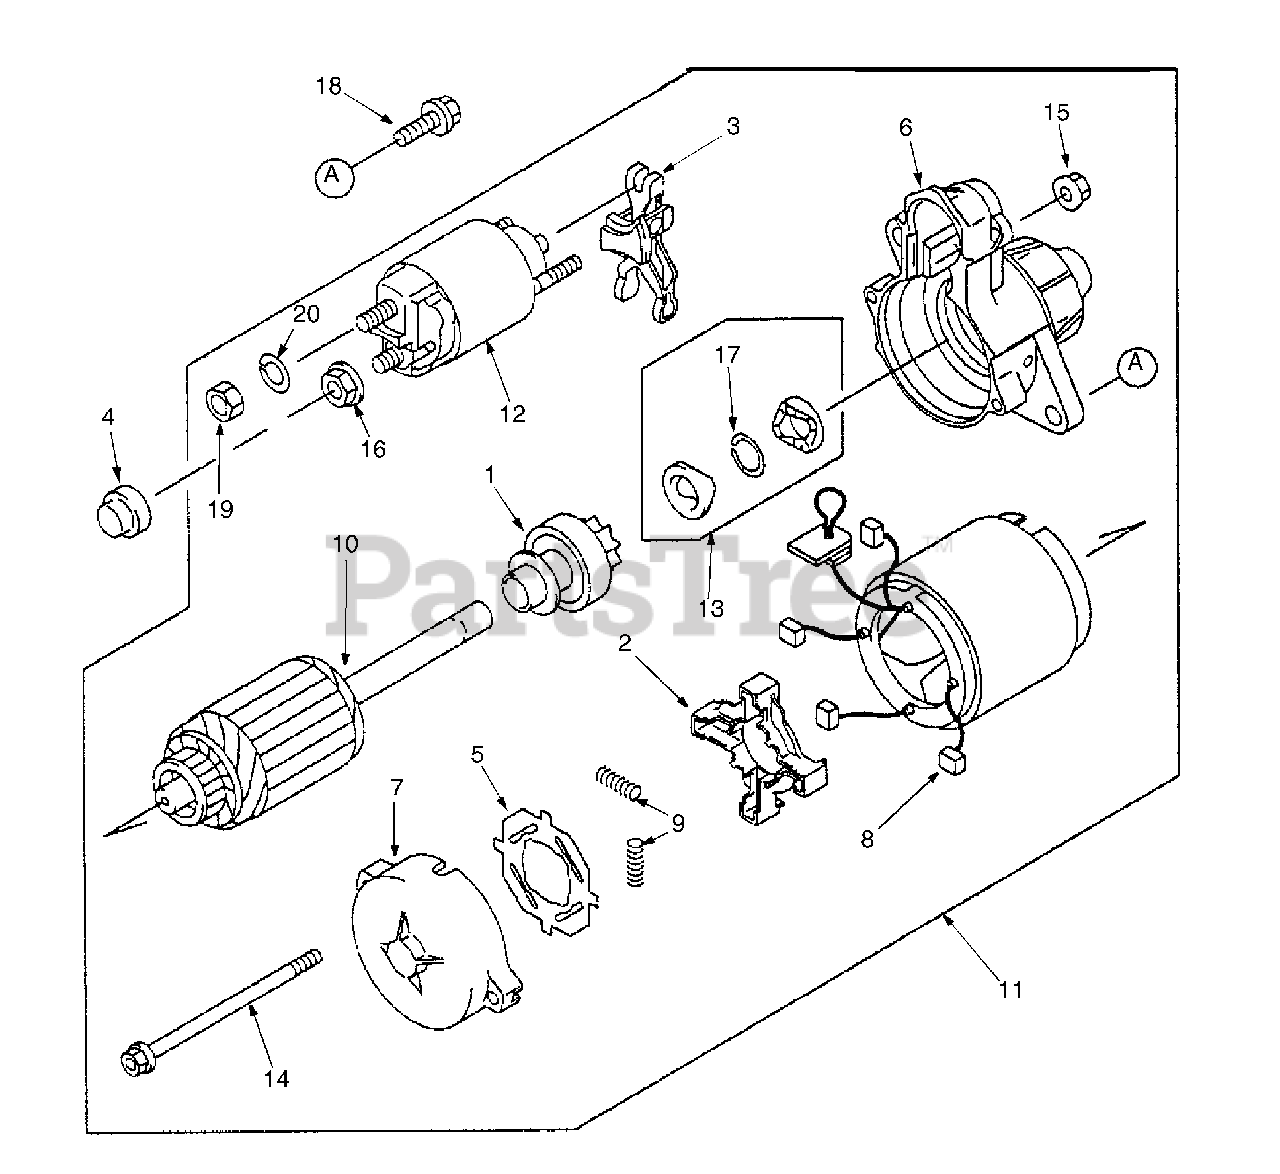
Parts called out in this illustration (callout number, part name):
1	Clutch Ass'y.
2	Holder, Brush
9	Spring, Brush
11	Starter, Complete
12	Switch, Solenoid
13	Stopper
18	Bolt, Flanged
19	Nut, Hex 8 MM
20	Washer, Spring, 8MM
